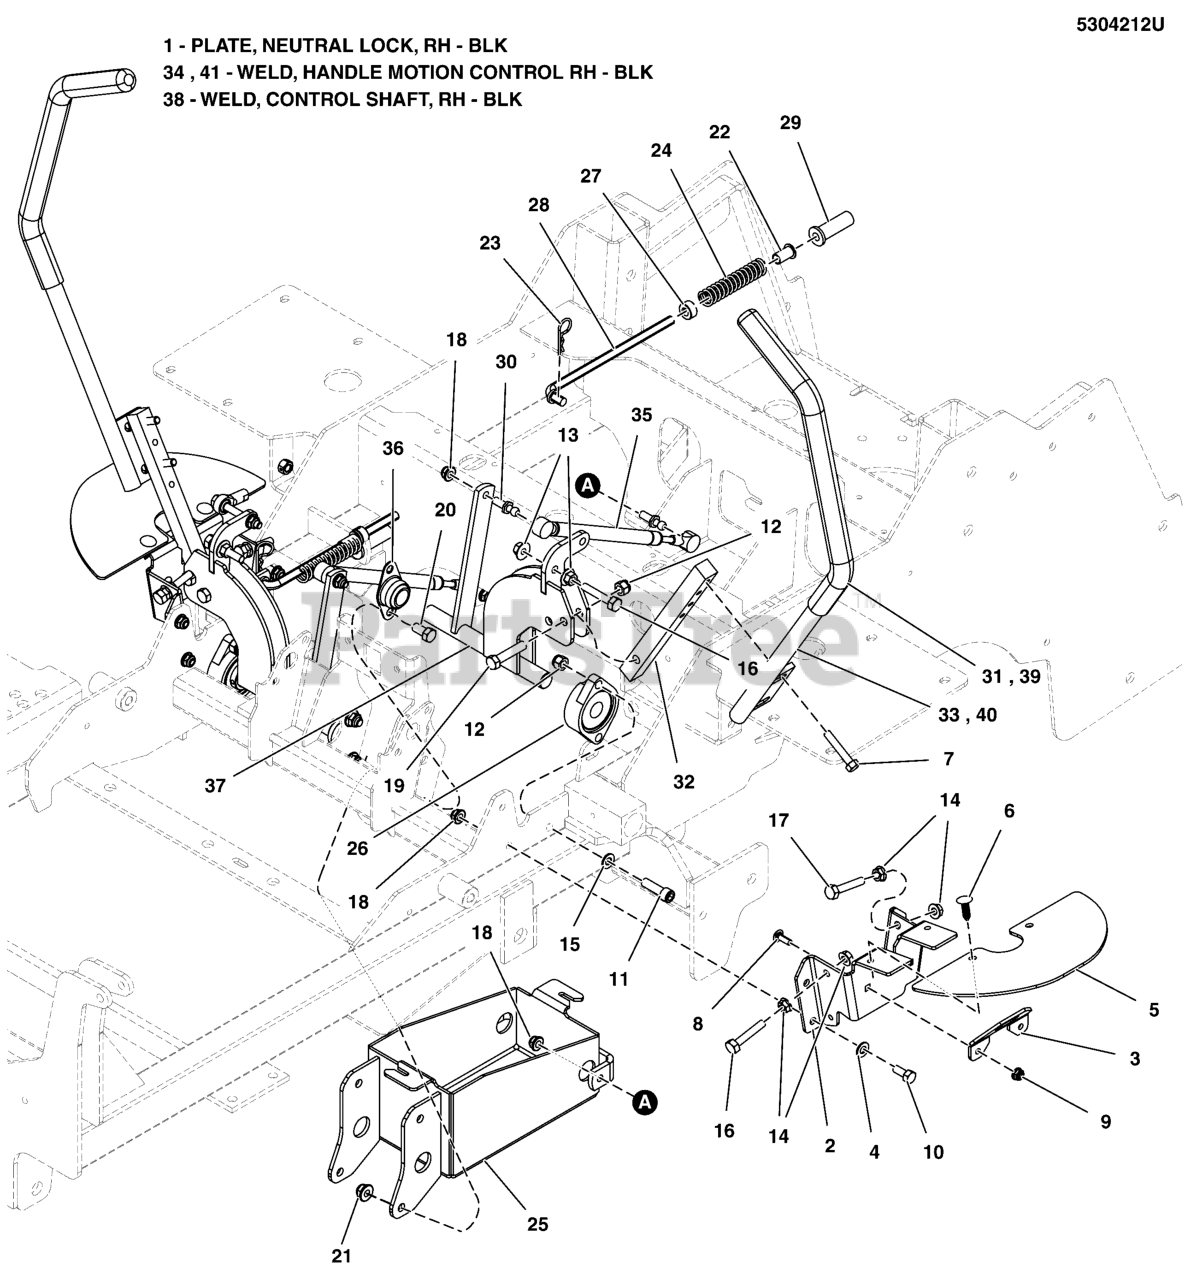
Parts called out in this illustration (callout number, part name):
1	PLATE, NEUTRAL LOCK, RH - BLK
2	PLATE, NEUTRAL LOCK, LH - BLK
3	BRACKET, SWITCH MOUNT - BLK
4	WASHER, 5/16" SAE
5	GUARD, RUBBER MOTION CONTROLS
6	PUSH RIVET (TREE TYPE), BLACK
7	SCREW, 5/16-18x0.750, GR5, WHIZ-LOCK, ZC
8	BOLT,1/4-20X.75,GR5,RH SH SQ NK,ZNC/CLR
9	NUT, 1/4-20 Hex Nylock Flange
10	BOLT, 5/16-18 X 3/4 GD5
11	BOLT, Allen Head, 3/8-16 x 1-1/4
12	NUT, 3/8-16 HEX NYLON LOCK
13	NUT, 5/16-18 HEX SERRATED FLANGE (LARGE)
14	NUT, 5/16-18 HEX SERRATED FLANGE (SMALL)
15	WASHER, 3/8 SAE
16	BOLT, 5/16-18 X 1-1/4 GD5 TFL, CZ
17	BOLT, 5/16-18 X 1-3/4 TFL, GD5 YZ
18	NUT, 5/16-18 HEX NYLOCK FLANGE NUT
19	BOLT, 3/8-16 X 1-3/4" GD5 CZ
20	BOLT, 3/8-16 X 1" GD5 CZ
21	NUT, 3/8 - 16 HEX NYLOCK FLANGE
22	BUSHING, FLANGE 3/8ID X 7/8 LONG
23	3/32 X 1-5/8 HAIR PIN CLIP
24	SPRING, REVERSE RETURN
25	WELD, BATTERY BOX - RED
26	BEARING, FLANGE
27	COLLAR, 3/8" Set
28	ROD, NEUTRAL RETURN, CZ
29	FLANGED BUSHING, 3/8IDX.63ODX.8125FL
30	10MM BALL STUD, 5/16-18 X 3/4 THDS
31	GRIP, FOAM, 3/4" ID, 16"" LONG
32	MOUNT, CONTROL ARM - BLK
33	WELD, HANDLE MOTION CONTROL LH - BLK
34	WELD, HANDLE MOTION CONTROL RH - BLK
35	DAMPENER, CONTROL,#(P6709/P3610)
36	BEARING, BRONZE FLANGE, 3/4"
37	WELD, CONTROL SHAFT, LH - BLK
37	WELD, CONTROL SHAFT, LOCKOUT, LH - BLK
38	WELD, CONTROL SHAFT, RH - BLK
38	WELD, CONTROL SHAFT, LOCKOUT, RH - BLK
39	GRIP, FOAM, 1" ID, 16" LONG
40	WELD, HANDLE MOTION CNTRL, 19.0, 1.0, LH - BLK
41	WELD, HANDLE MOTION CNTRL, 19.0, 1.0, RH - BLK
